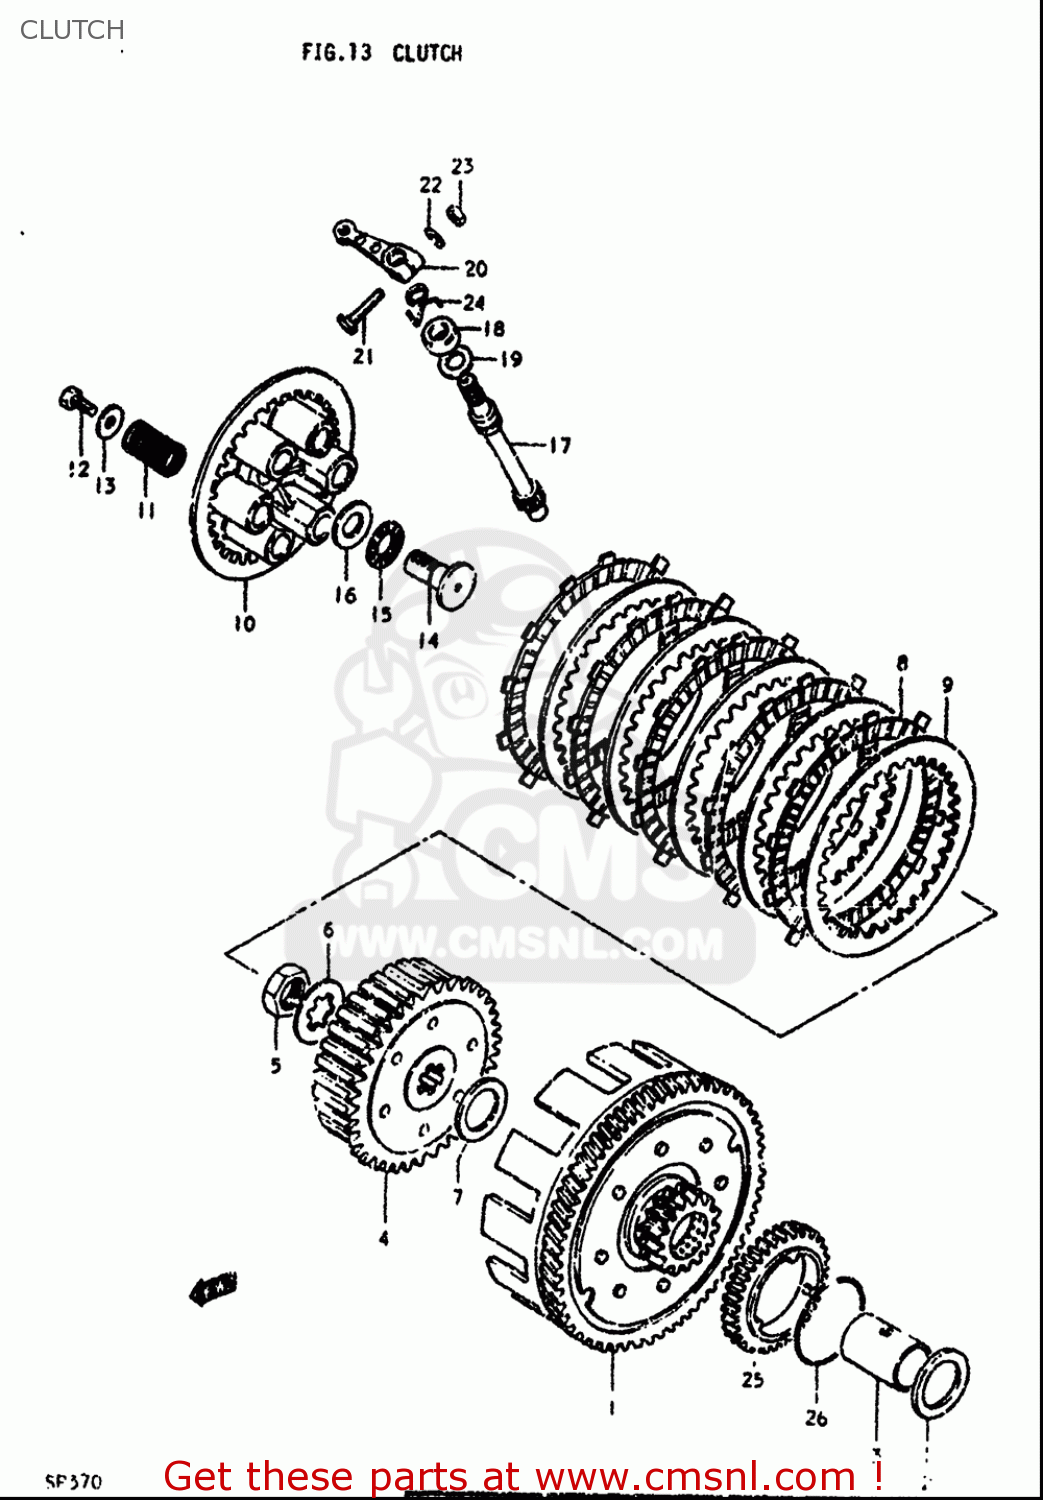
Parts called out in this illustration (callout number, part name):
1	GEAR ASSEMBLY,PRIMARY DRIVE
2	WASHER
5	NUT
6	WASHER,LOCK
7	WASHER(20X38X2)
8	PLATE,CLUTCH DRIVE(T:3.5) (NAS)
9	PLATE,CLUTCH DRIVEN(T:2.0) (NAS)
10	DISC,CLUTCH PRESSURE
11	SPRING
12	BOLT
14	RACK,CLUTCH RELEASE
15	BEARING(15X28X2)
16	WASHER(15.5X28X1)
17	PINION,CLUTCH RELEASE
18	SEAL,OIL (12X22X9)
19	SPACER(14X19X18)
20	ARM,CLUTCH RELEASE
21	BOLT
22	WASHER
23	NUT
26	CIRCLIP
